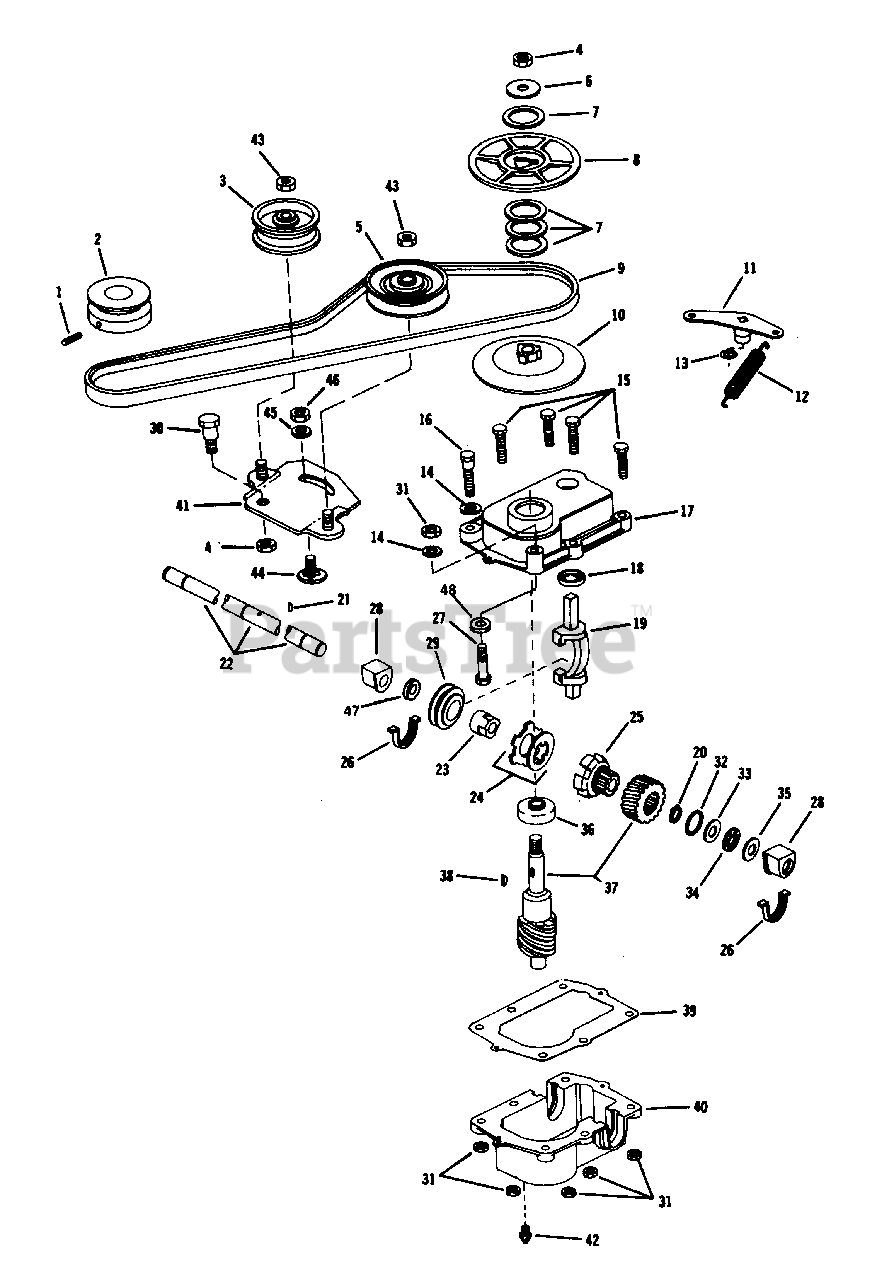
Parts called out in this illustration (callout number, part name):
1	Set Screw
2	Pulley-Engine
3	Pulley-Idler Variable Speed
4	Nut
5	Idler-V-Belt
6	Washer
7	Washer
8	Pulley Half-Upper
9	V-Belt
10	Pulley Half-Lower
11	Shift Arm
12	Spring-Extension
13	GRing
14	Washer
15	Screw-Hex Hd. Cap
16	Bolt-Shoulder
17	Gear Case-Upper
18	Seal Guide
19	Fork-Shift
20	Ring-Retaining
21	Pin
22	Drive Shaft
23	Driven Sleeve
24	Disc Clutch Kit
25	Driver
26	Packing
27	Screw
28	Bearing-Gearcase
29	Collar
30	Bolt-Shoulder
31	Nut
32	Washer-Thrust
33	Washer-Thrust
34	Bearing-Thrust
35	Washer-Thrust
36	Bearing
37	Worm Wheel and Shaft Ass'y.
38	Key
39	Gasket
40	Gear Case-Lower
41	Idler Plate
42	Lubrication Fitting
43	Nut-Thin
44	Bolt-Sq. Neck
45	Washer
46	Nut
47	Washer
48	Lockwasher
